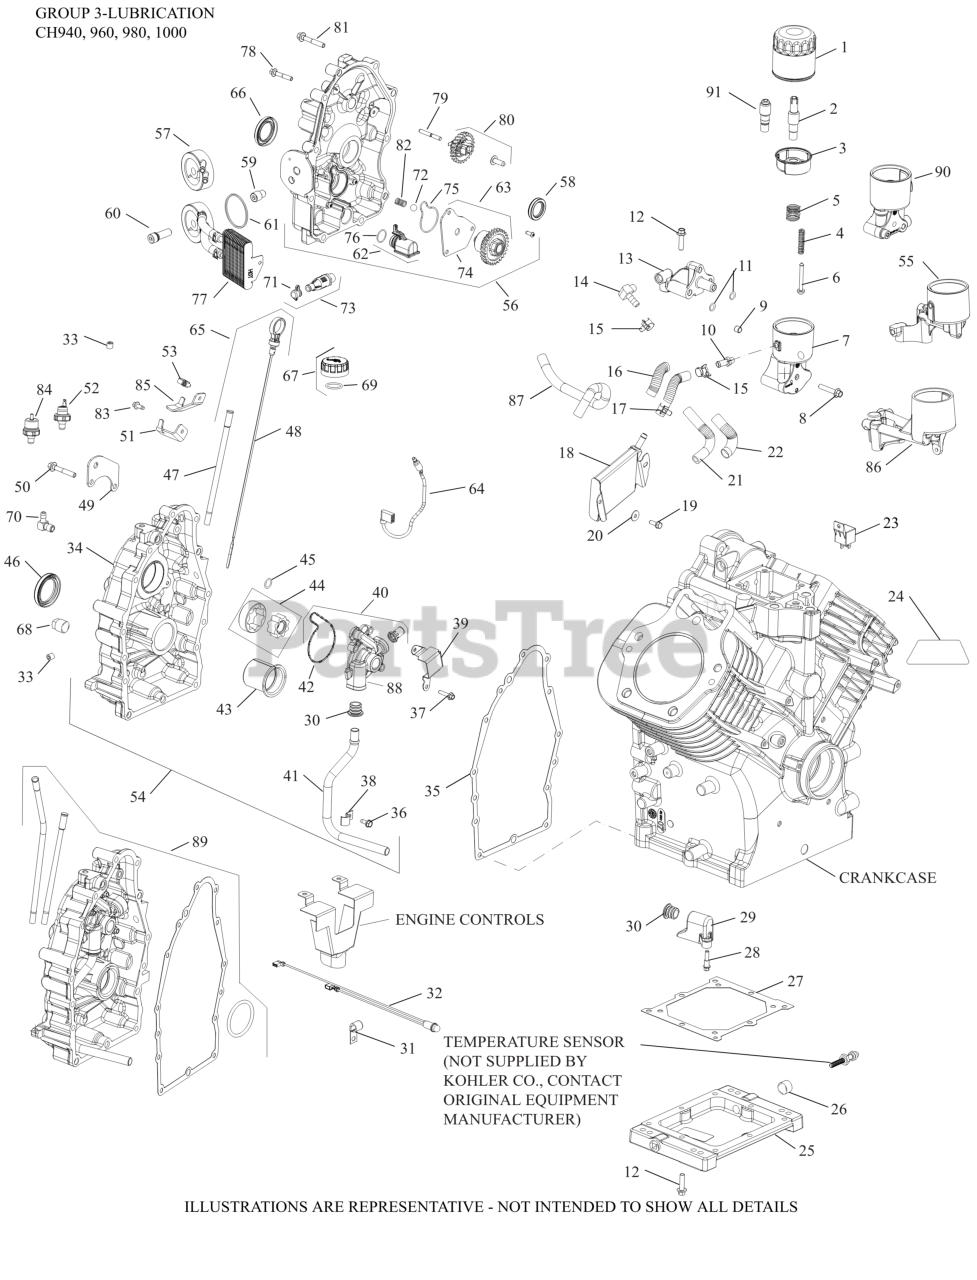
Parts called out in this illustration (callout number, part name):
1	OIL FILTER
2	NIPPLE, OIL FILTER ASSEMBLY-(#6213606S)
3	CUP, OIL FILTER ASSEMBLY
4	SPRING, OIL FILTER VALVE
5	SPRING, OIL FILTER CUP
6	VALVE, OIL FILTER
10	FITTING, BARBED
11	O-RING, OIL PICK-UP
12	SCREW, FLG M8X1.25X30
16	SLEEVE, ANTI ABRASION-USE 25 431 12-S
17	HOSE, OIL RETURN
18	COOLER, OIL ASSEMBLY
19	SCREW, TAP M6X1.7X18
20	WASHER, FLAT 1/4"
21	HOSE, OIL SUPPLY
22	SLEEVE, ANTI ABRASION-USE 25 431 12-S
25	OIL RESERVOIR
26	BUSHNG,REDCR 1/2"-1/8" NPT STL
27	GASKET, OIL RESERVOIR
28	SCREW, SHD THD FRM M6X.0X6.5
29	HOUSING, OIL PICK-UP ASSEMBLY
30	SEAL, PICK-UP TUBE
33	PLUG, CTSK PIPE 1/8"
34	KIT, CLOSURE PLATE
35	GASKET, OIL PAN
41	TUBE, OIL PICK-UP
42	O-RING, OIL PUMP HOUSING
44	PUMP ASSEMBLY, OIL/GEROTOR
46	SEAL, OIL-(#2503218S)
47	KIT, DIPSTICK TUBE
49	STRAP, LIFTING
51	BRACKET, DIPSTICK TUBE
52	SWITCH, OIL PRESSURE
53	CLAMP, HOSE (KM)-USE 25 237 31-S
55	KIT, OIL FILTER HOUSING
81	SCREW, HEX FLANGE
83	SCREW, THREAD FORMING
90	HOUSING, OIL PUMP MACH-USE 62 081 38-S
